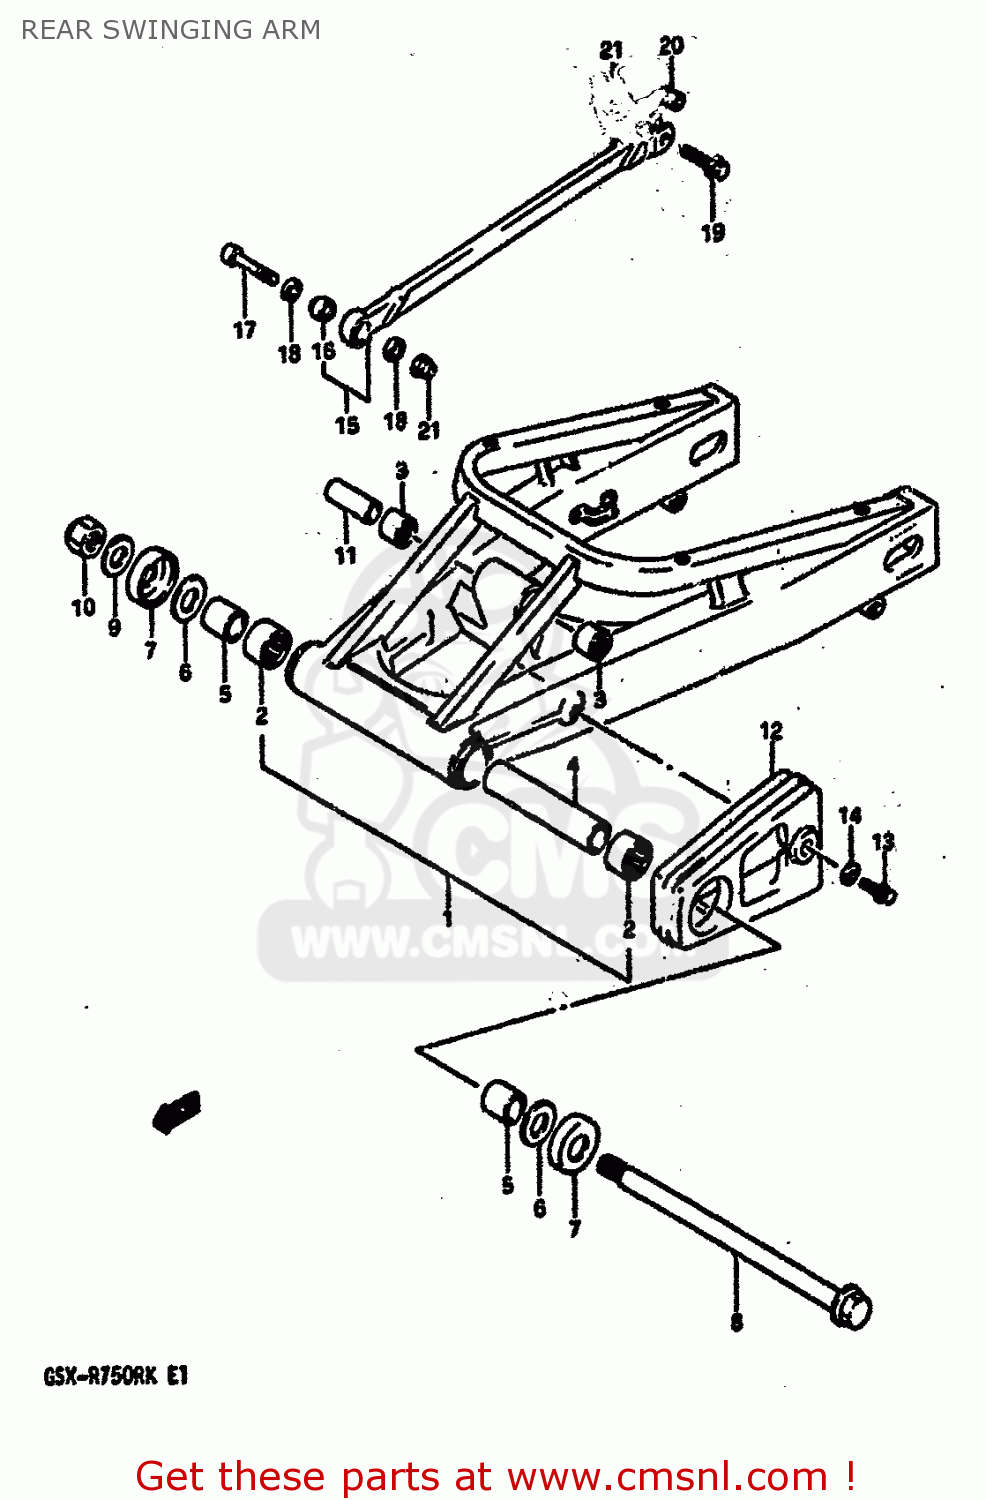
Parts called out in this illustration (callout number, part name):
1	SWINGING ARM ASSY,REAR
2	BEARING(25X33X30)
3	BEARING(20X27X23.5)
4	SPACER,RR SWGARM PIVOT CTR
5	SPACER,RR SWGARM PIVOT BERRING
6	WASHER
7	DUST SEAL,RR SWGARM PIVOT
8	SHAFT,REAR SWING ARM PIVOT
9	WASHER
10	NUT
11	SPACER,RR CUSHION LEVER
12	BUFFER,CHAIN TOUCH DEFENCE
13	BOLT
14	WASHER
15	TORQUE LINK SET,REAR
16	SPHERICAL BEARING,TORQUE
17	BOLT(8X48)
18	19
19	BOLT(8X35)
20	SPACER,RR TORQUE LINK RR
21	NUT
